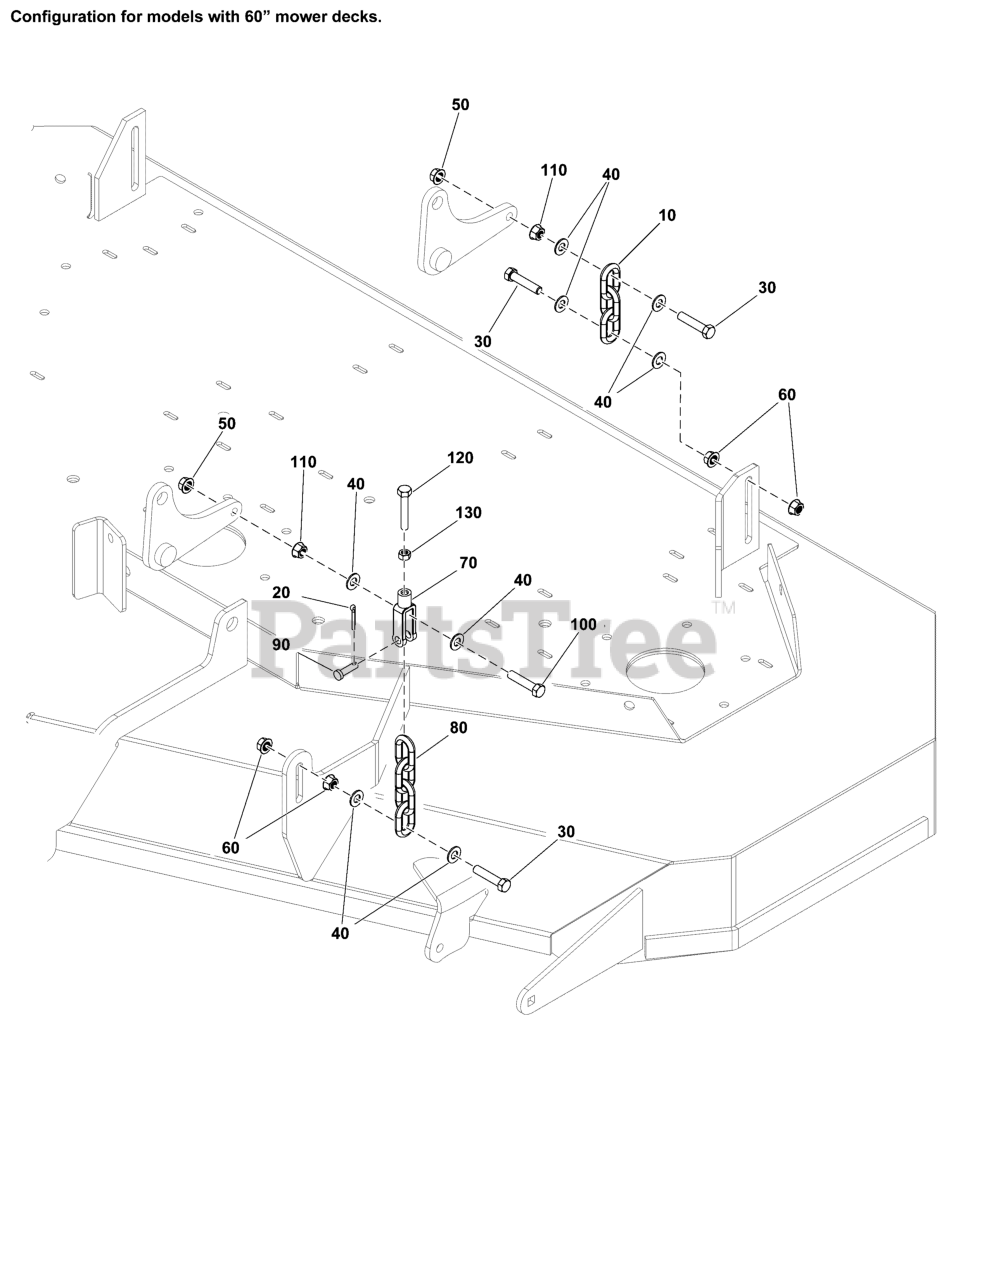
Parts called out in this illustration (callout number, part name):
10	CHAIN, 5/16" GD30, 3
20	PIN, COTTER, 3/32X.75
30	BOLT, 3/8-16 X 1-3/4"
50	NUT, 3/8-16 HEX NYLOCK
60	NUT, 3/8-16 HEX SERRA
70	CLEVIS, 5/16-18, 3/8
80	CHAIN, 5/16", 4 LINKS
90	PIN - CLEVIS
100	CAPSCREW, 3/8-16X2
110	NUT, 3/8-16 HEX JAM
120	BOLT, 5/16-18X2
130	NUT, 5/16-18 HEX JAM
